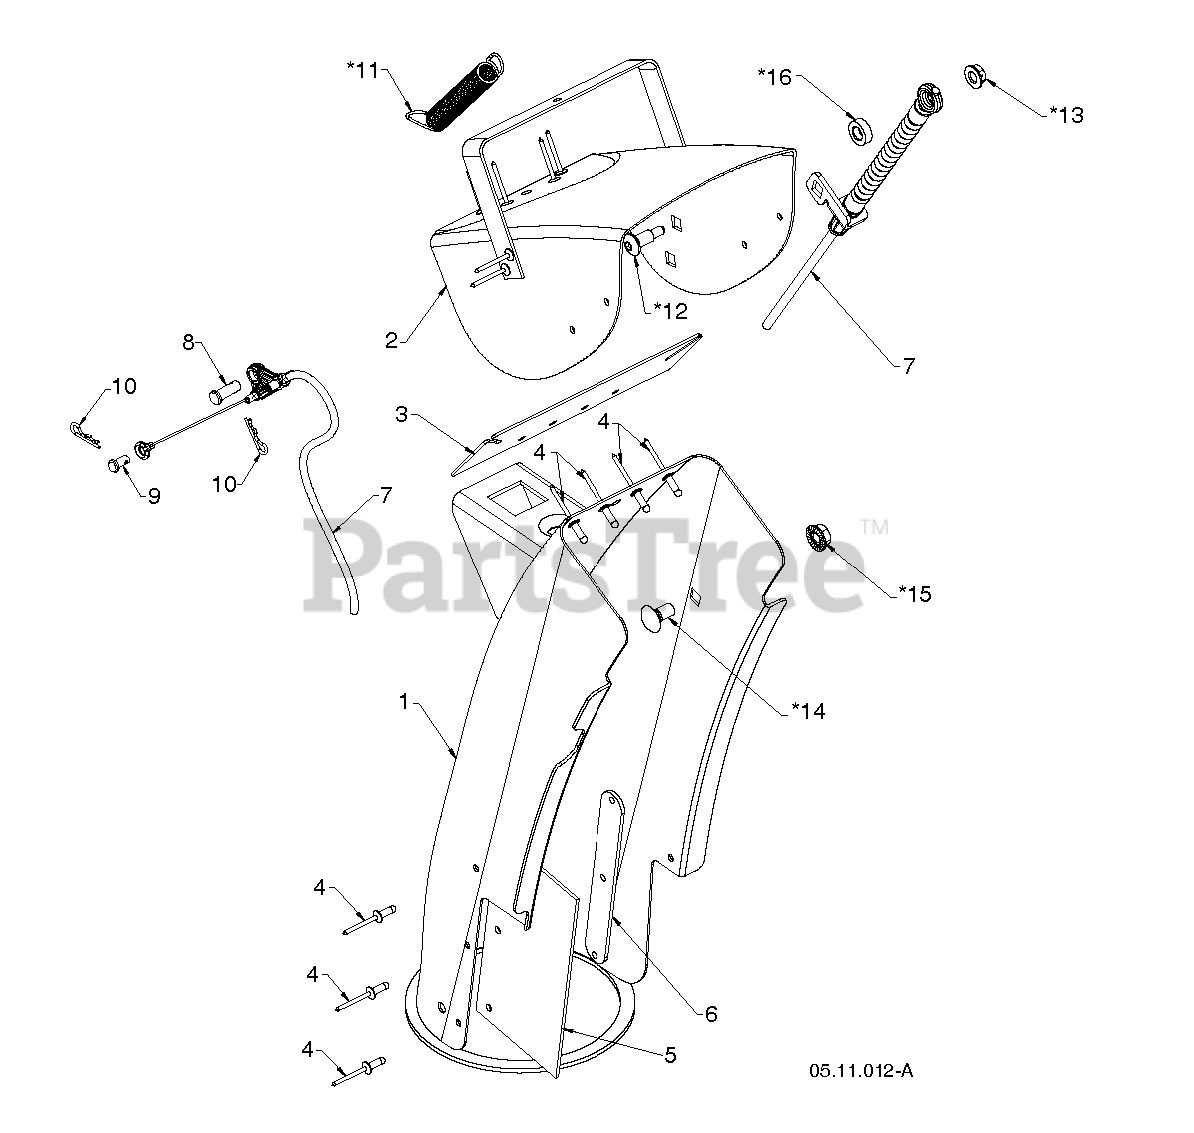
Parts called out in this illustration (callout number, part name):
1	ASM.CHUTE/DEFLECTOR.668
8	PIN CLEVIS 5/16X.875
9	PIN CLEVIS .25 X .31
10	HAIRPIN.SOFT.ZINC.059X1.125
